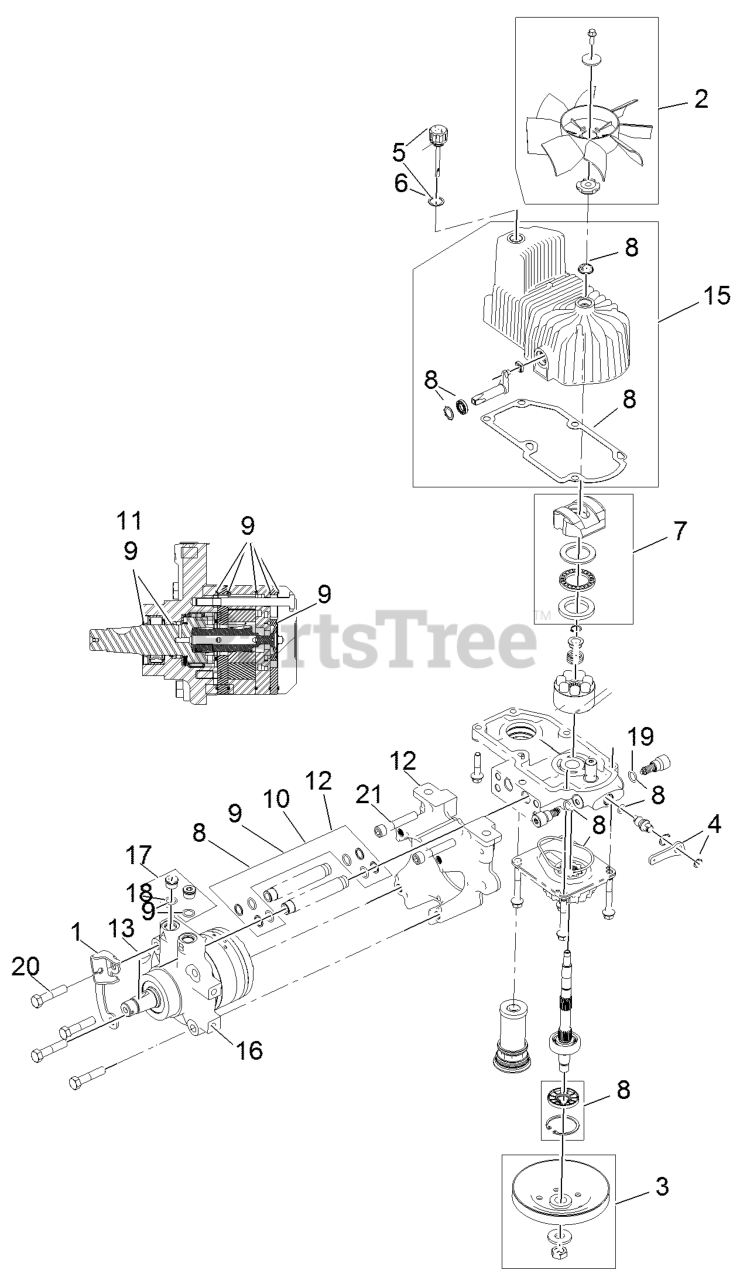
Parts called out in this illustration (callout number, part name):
1	BRACKET-ANCHOR, CABLE
2	FAN KIT
3	PULLEY KIT
4	HANDLE-BYPASS VALVE, HYDRO
5	DIPSTICK-HYDRO W/GASKET
6	GASKET-DIPSTICK, HYDRO
7	SWASH BLOCK KIT
8	PUMP SEAL KIT
9	MOTOR SEAL KIT
10	TUBE SEAL KIT
11	Output Shaft Seal Kit
12	Nose Cup-Uht
13	Key-Woodruff 5/16 X 1
15	Housing-Rh
16	Motor-Hydraulic Rh 240cc
17	Magnetic Plugs Service Kit
19	O-Ring-Check Valve
20	Screw-Hh 1/2-20 X 2 1/4
21	Screw-Hsh 1/2-20 X 2 3/4
